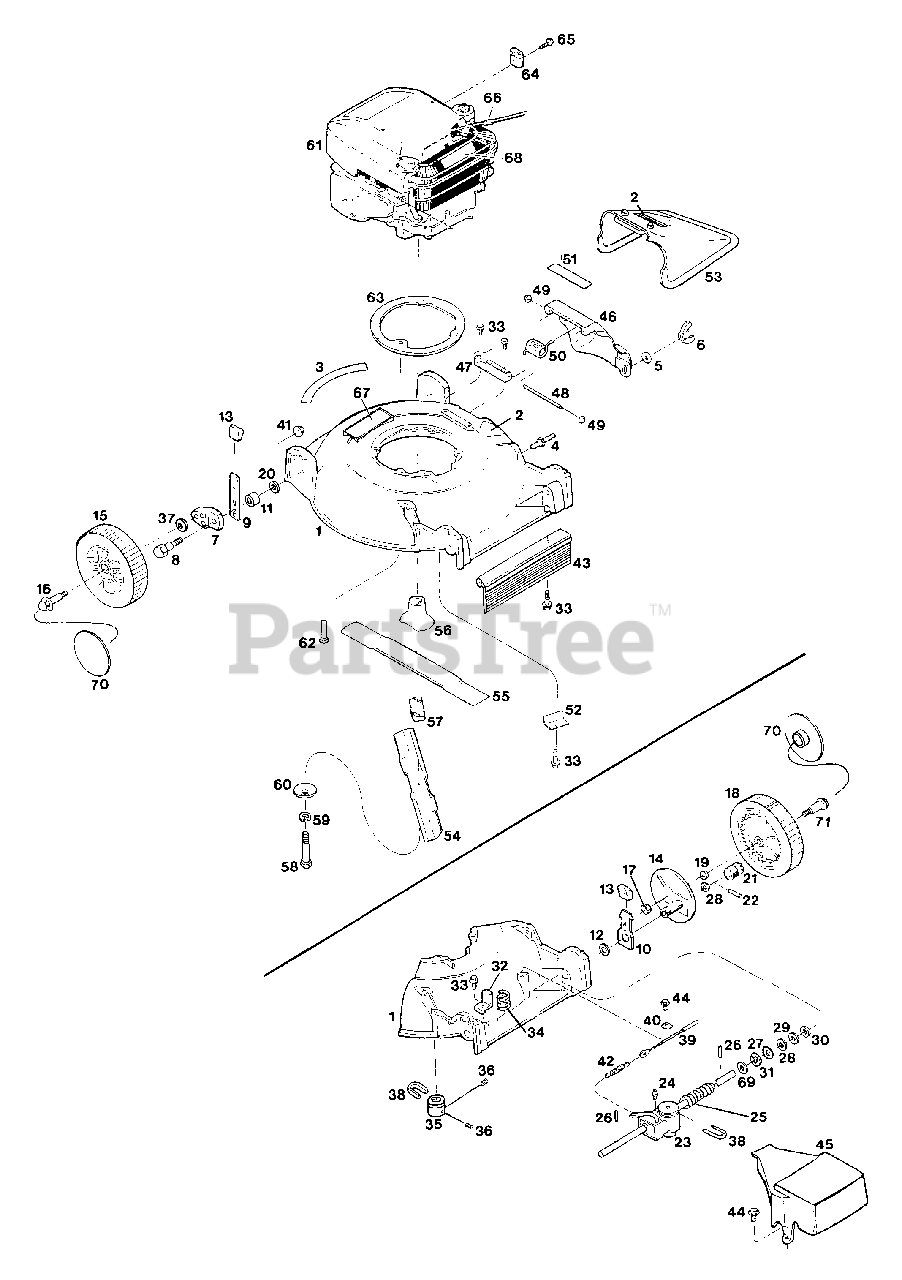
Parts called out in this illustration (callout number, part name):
1	Deck - 20" push
2	Decal - DANGER
3	Decal - logo
4	Stud - 1/4-20 x 3/4
5	Washer - flat 1/4
6	Nut - wing 1/4-20 nylok
7	Arm - wheel mount
8	Bolt - shoulder 5/16-18 x 1-5/8
9	Lever - height adjuster (Left Front & Right Rear)
10	Lever - height adjuster Right Rear
11	Spacer - lever
12	Spacer - lever, rear
13	Tip - adjuster lever
14	Support - drive wheel
15	Wheel - 8" with tire
16	Bolt - wheel 3/8-16 x 2 1/8
17	Nut - hex 3/8-16 lock
18	Wheel - 8" power propelled
20	Washer - flat 5/16
21	Pinion - drive RH
22	Pin - drive
23	Transmission - 1 speed
24	Vent - Transmission
25	Shield - dust, plastic
27	Washer - shim
28	Washer - flat 9/16, thin
29	Washer - flat 9/16, thick
31	E - Ring
32	Bracket - Transmission
33	Screw - hex tap 1/4-20 x 3/4
34	Spring - compression
35	Pulley - drive
37	Washer - Belleville
38	Belt - traction drive
39	Cable - traction drive
40	Clamp - drive cable
41	Nut - hex 5/16-18 flng lock
42	Spring - extension
43	Shield - trailing, plastic
45	Cover - Rear Drive
46	Cover - Mulch
47	Bracket - Cover hinge
48	Pin - hinge
49	Nut - push on 1/4
50	Spring - Mulch cover
51	Decal - DANGER, Mulch cover
52	Cover - belt opening
53	Deflector - discharge opening
54	Blade - mulcher 20
55	Blade - recutter
56	Adaptor - blade
57	Spacer - blade
58	Bolt - hex 3/8-24 x 3-1/2 Gde 8
59	Washer - split lock 3/8 HD
60	Washer - conical 3/8
61	Engine
62	Bolt - hex 3/8-16 x 1-3/4 sems
63	Ring - engine to deck
64	Clamp - cable
65	Screw - tap #10-16 x 5/8
66	Stop - rope
67	Decal - recycle mulcher
68	Decal - blade warning
